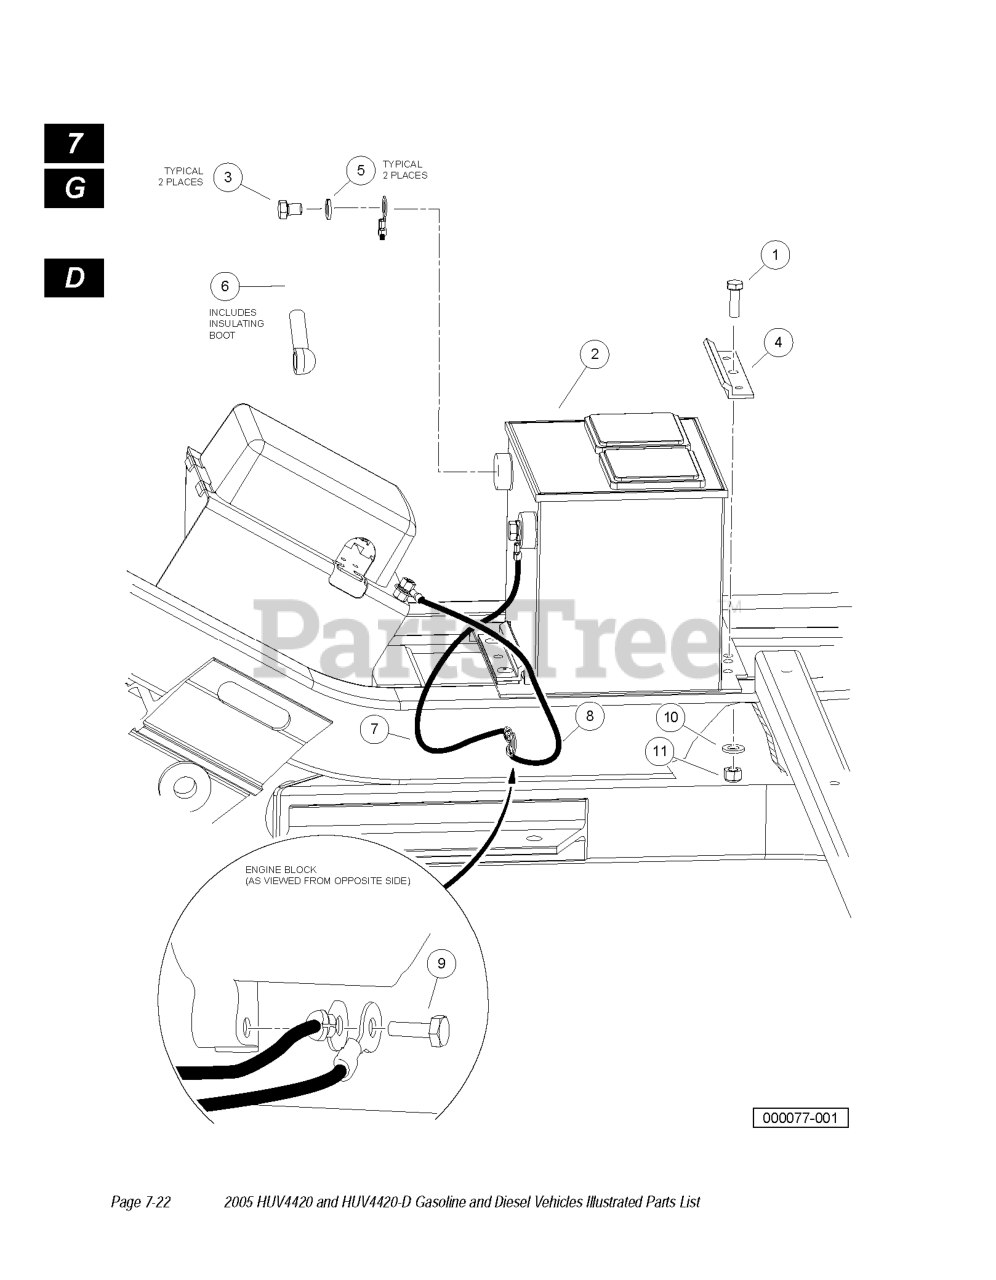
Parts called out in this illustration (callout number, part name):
1	SCREW HEX CAP
2	BATTERY, 12 VOLT
4	CLAMP - BATTERY
5	LOCKWASHER, 3/8 STAINLESS STL
6	WIRE ASM, #6 RED, AWD
7	WIRE ASM, #6 BLK, AWD, 300
8	WIRE ASM, #6 BLK, AWD, 250
9	BOLT, M6 X 1 X 16 LOCTITE
10	WASHER, 5/16 TYPE A FLAT
11	LOCKNUT, 5/16-18 NYLON INSERT
